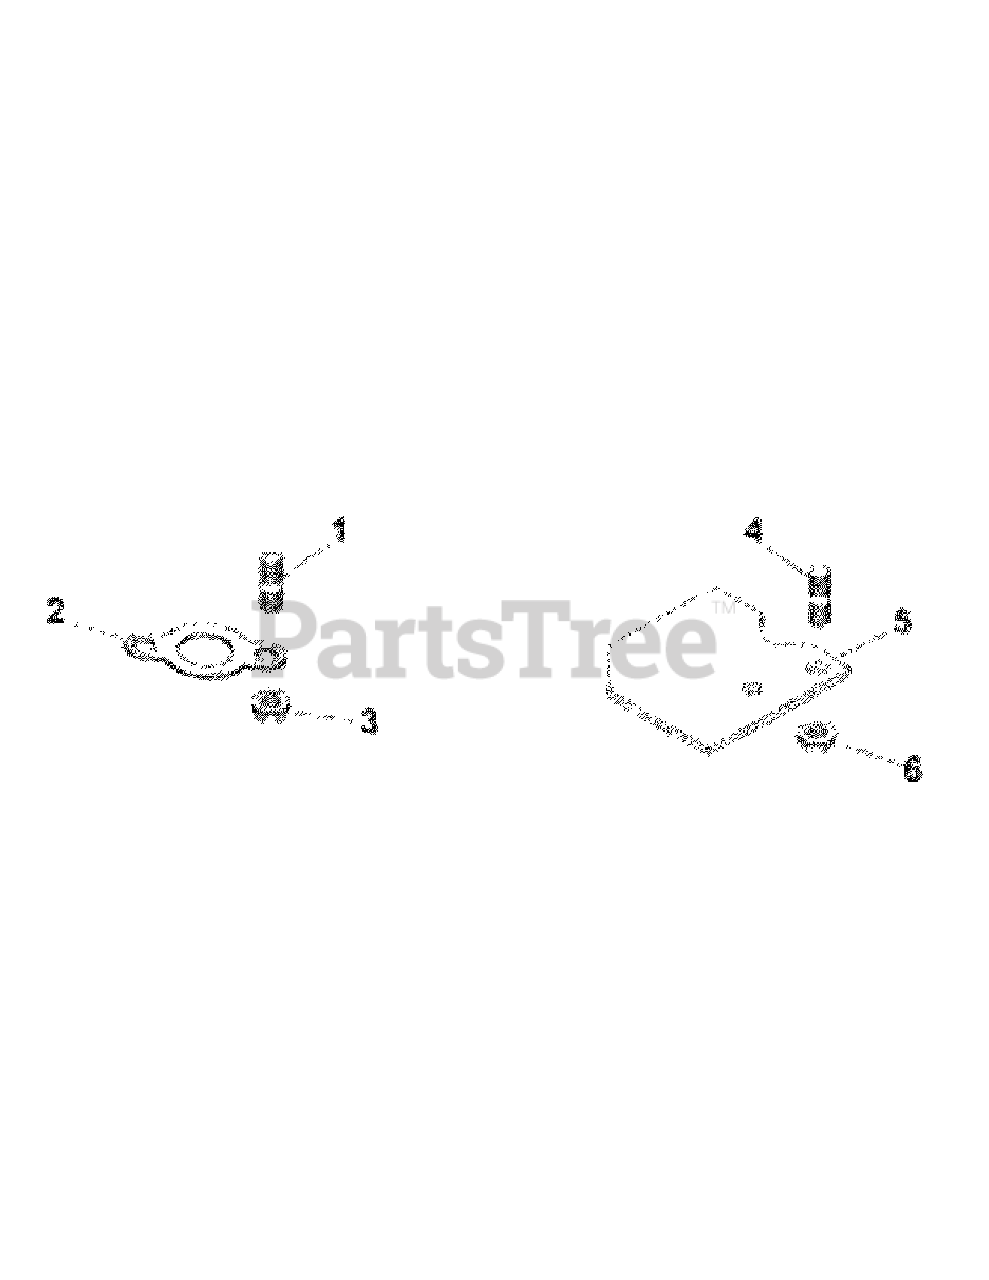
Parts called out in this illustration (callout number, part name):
2	Exhaust Gasket
3	Muffler Mounting
4	Exhaust Stud
5	Heat Deflector
6	Hex Flange Nut
